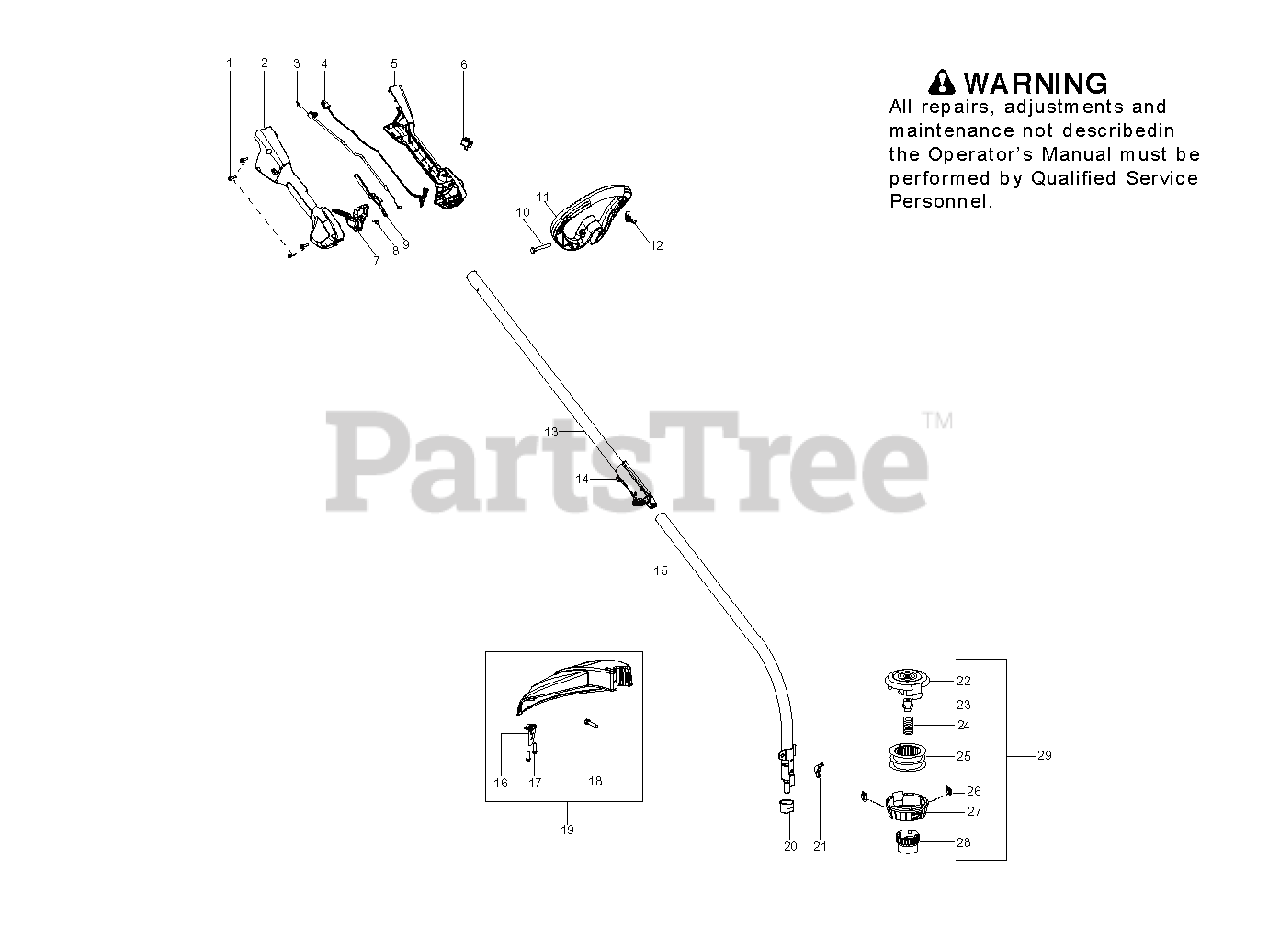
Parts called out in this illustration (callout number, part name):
1	SCREW M4 X 1.75 PT 16MM
2	THROTTLE HSG RH BLACK
3	ASSY THROTTLE CABLE TRMR
4	ASSY WIRE HARNESS
5	THROTTLE HSG LH BLACK
6	STOP SWITCH
7	TRIGGER YELLOW
8	SPRING TRIGGER
9	LOCKOUT YELLOW
10	BOLT 1/4-20 X 2 SQUARE
11	HANDLE ASSIST 1"
12	WINGNUT, TYPE 2
13	UPPER DRIVESHAFT
14	ASSY COUPLER BLACK
15	ASSY SHAFT LOWER CURVED
16	LINE CUTTER
18	BOLT, TYPE 2
19	KIT LINE SHIELD CURVED
21	WINGNUT, TYPE 2
22	Trimmer Head Housing
25	ACCY PPR TNG VII SPOOL .080
26	EYELET (SUBS TO COVER W/EYELET
27	COVER
29	PPR TNG 7 .080 HEAD RH
